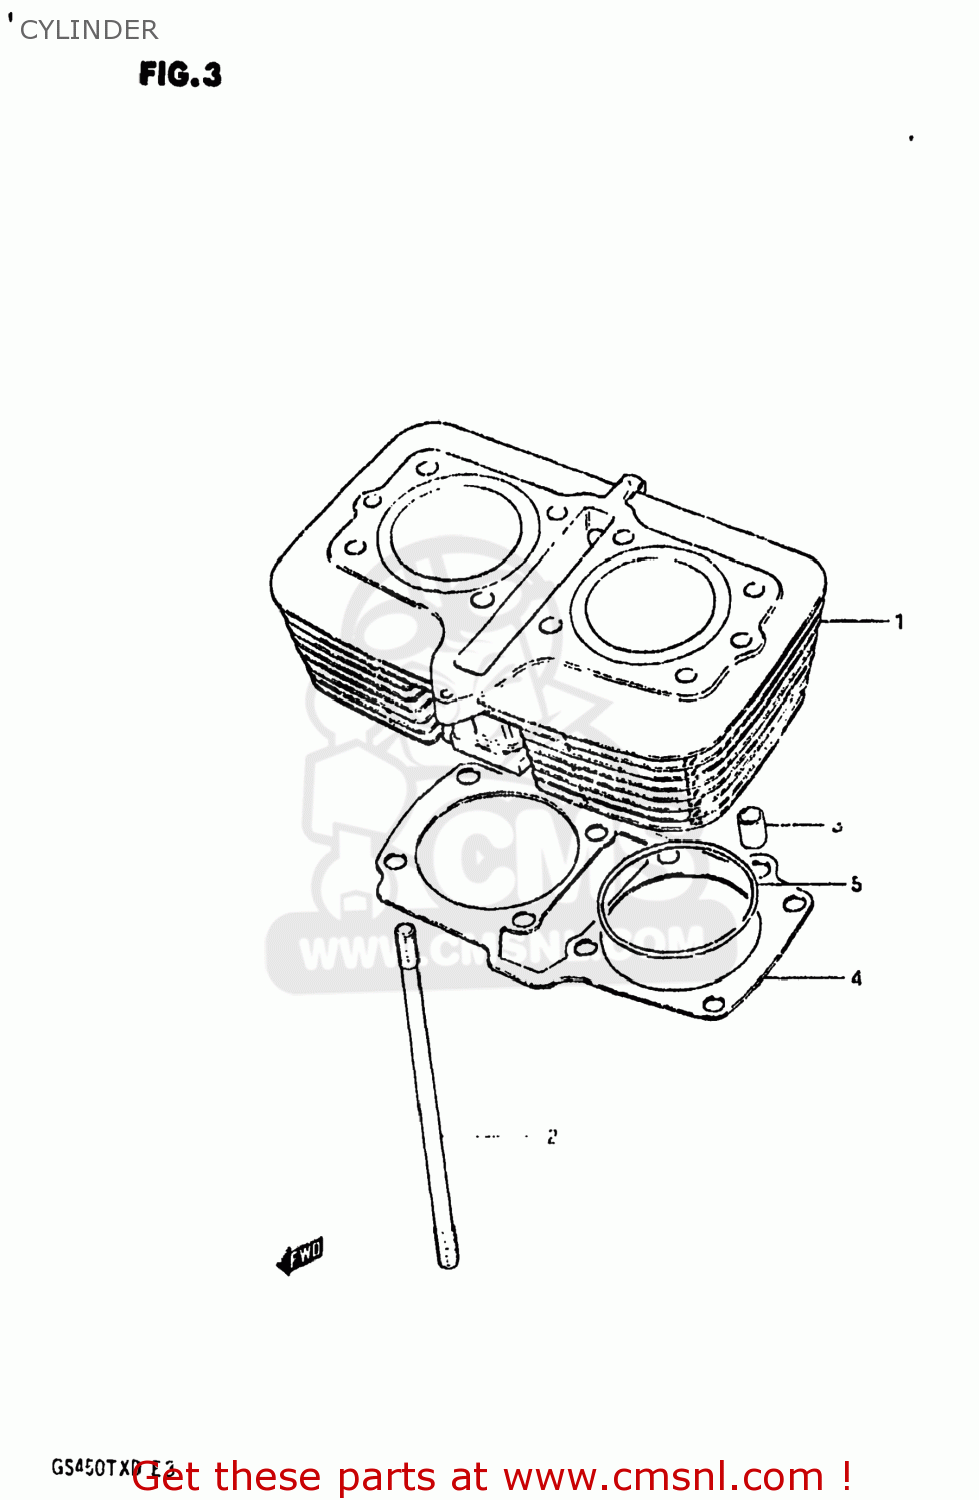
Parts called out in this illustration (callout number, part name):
1	CYLINDER
2	STUD
3	PIN
4	GASKET,CYLINDER (MCA)
5	O RING(D:2,ID:74)
